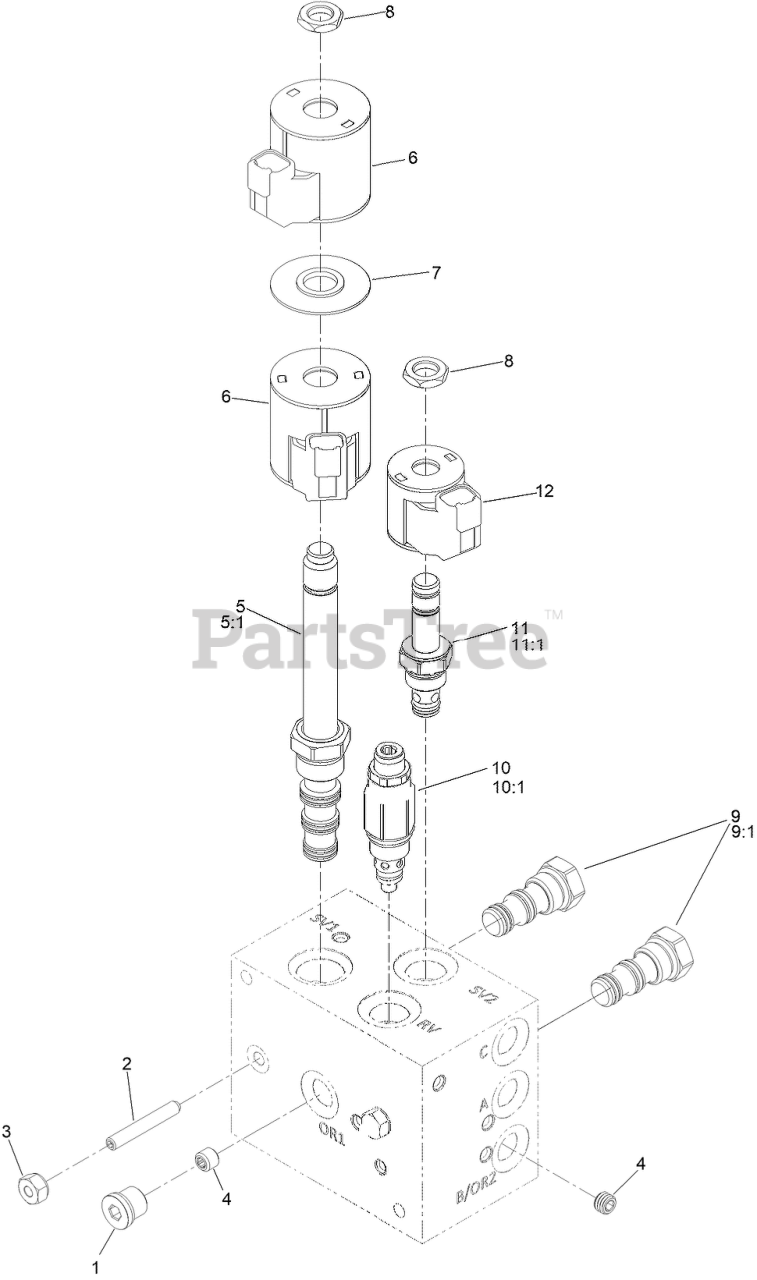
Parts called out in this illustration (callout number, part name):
1	PLUG-HYD, SAE
2	SCREW-SET
3	Nut-Sealing, Hex
4	PLUG-ORIFICE
5	Solenoid Valve ASM
5:1	SPOOL VALVE SEAL KIT
6	COIL-12V
7	Spacer-E Coil
8	NUT-COIL
9	PO CHECK VALVE
9:1	SEAL KIT
10	VALVE-HYD, PRESSURE RELIEF
10:1	SEAL KIT
11	VALVE-HYD, SOLENOID, NC
11:1	SEAL KIT
